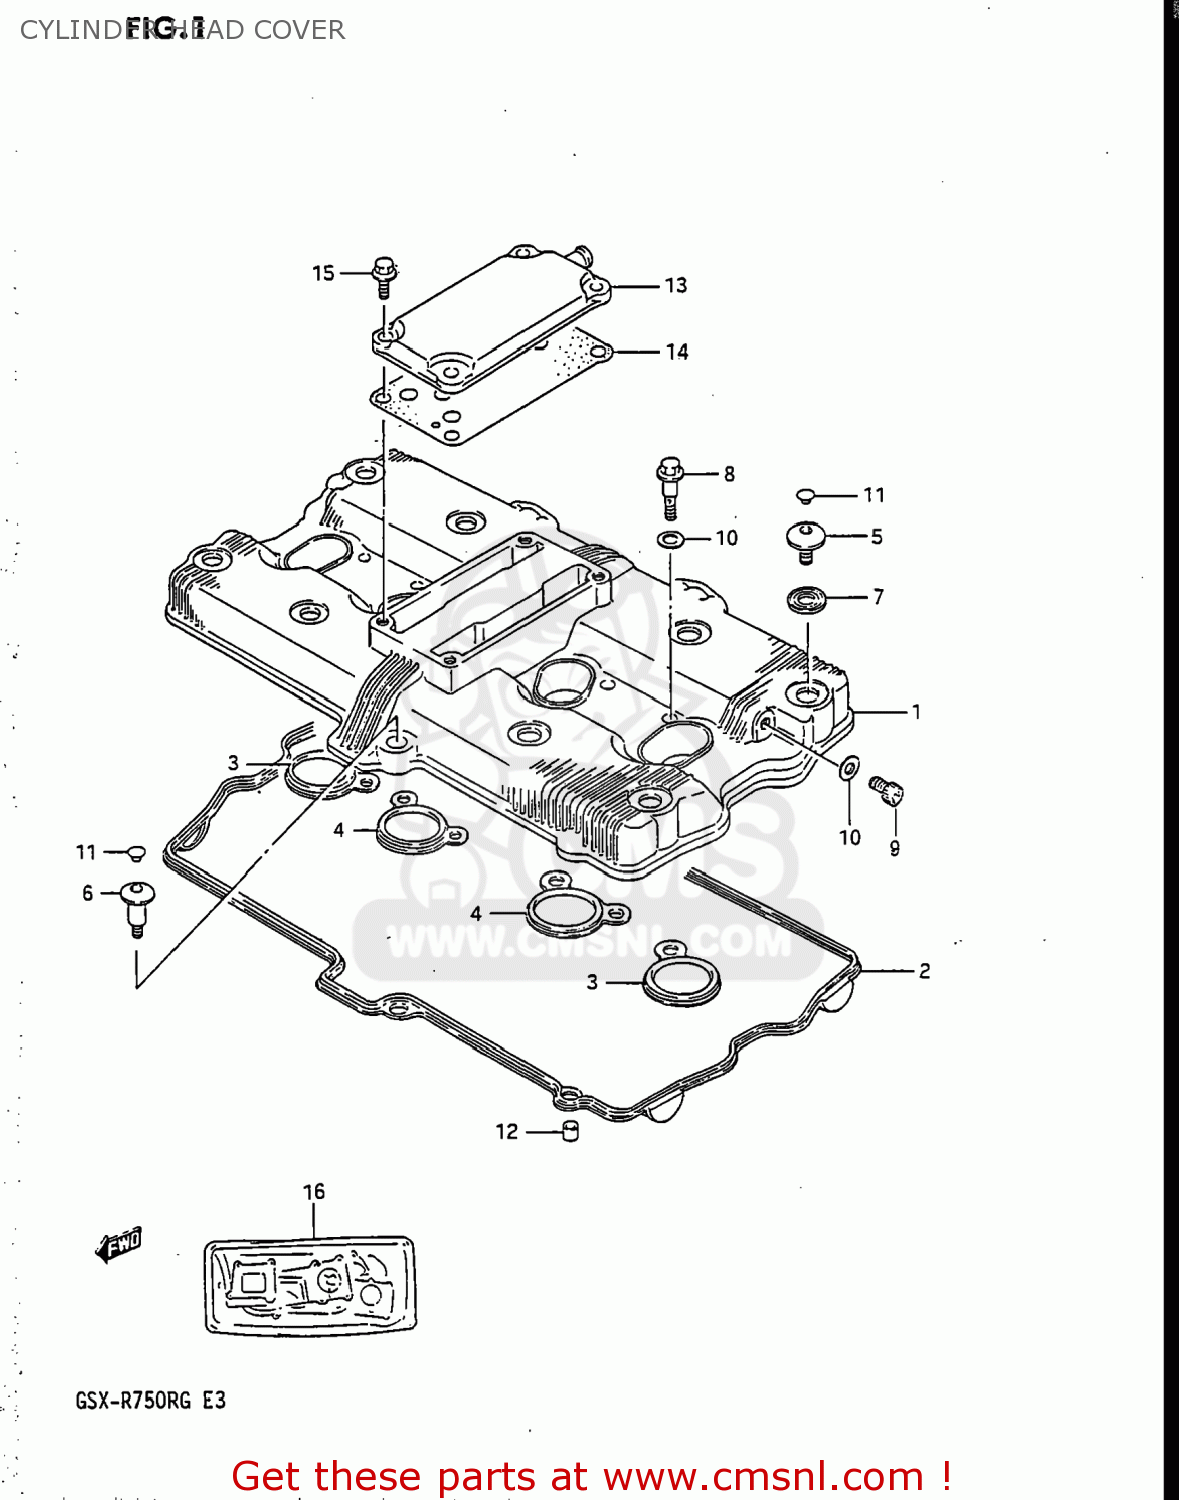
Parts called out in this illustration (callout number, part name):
1	COVER,CYLINDER HEAD
2	GASKET,CYLINDER HEAD COVER (NAS)
3	GASKET (NAS)
4	GASKET,HEAD COVER NO.3 (NAS)
5	BOLT(7X17.5)
6	BOLT(7X31)
7	WASHER
8	BOLT,UNION 8X35
9	PLUG, HEAD COVER
10	GASKET 8.2X14X1 (NAS)
11	CAP(OD:10)
12	PIN
13	COVER,BREATHER
14	GASKET (NAS)
15	BOLT
16	GASKET SET
